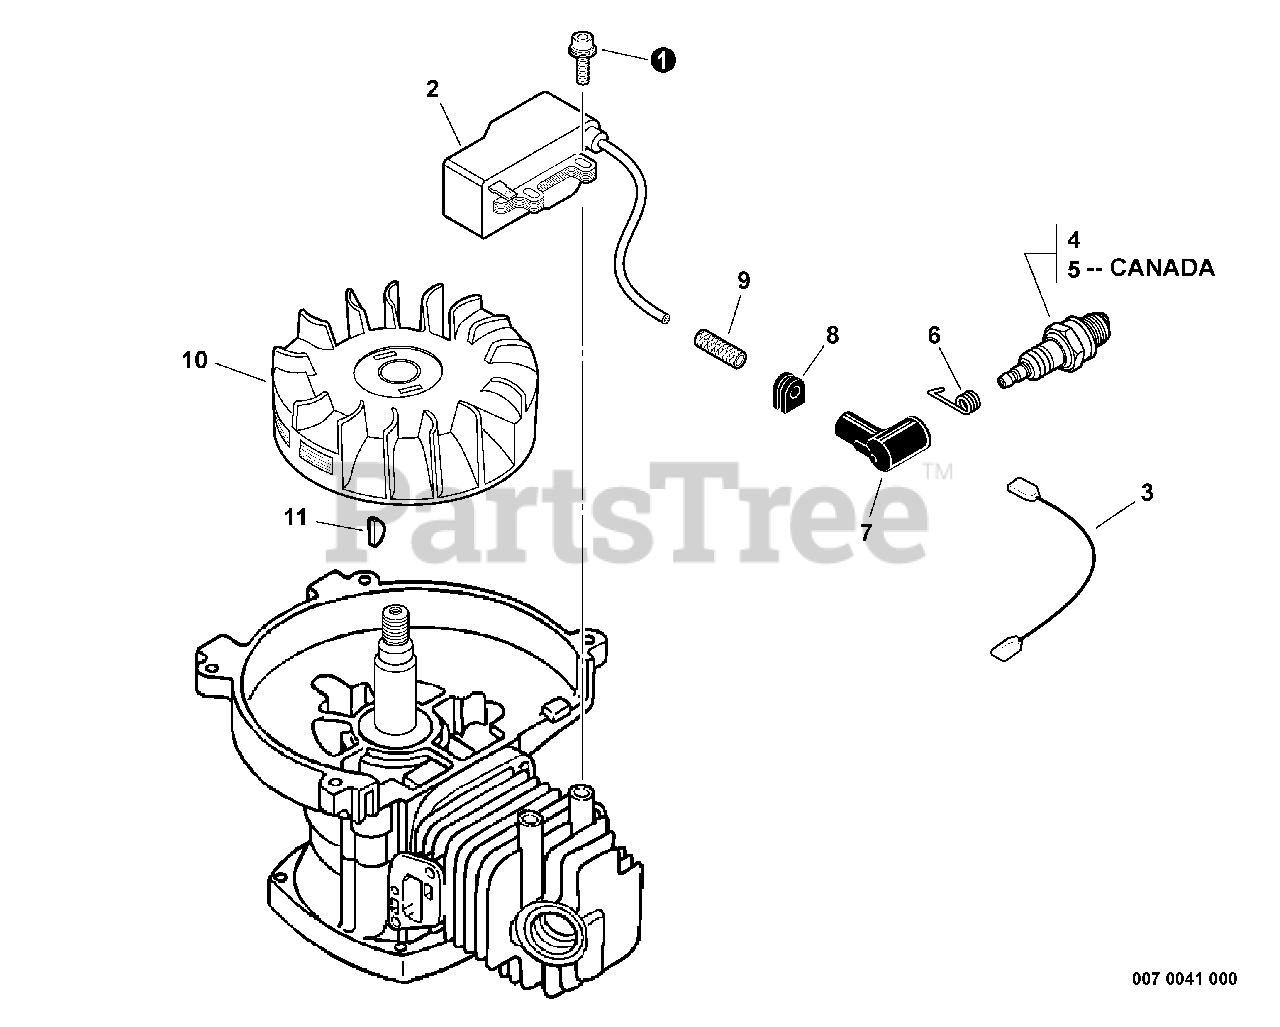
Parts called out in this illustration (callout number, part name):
1	BOLT 4×20
2	COIL, IGNITION
3	LEAD
4	SPARK PLUG - BPM8Y
5	SPARK PLUG - BPMR8Y
6	TERMINAL, SPARK PLUG
7	CAP, SPARK PLUG
9	TUBE, INSULATOR
10	FLYWHEEL
